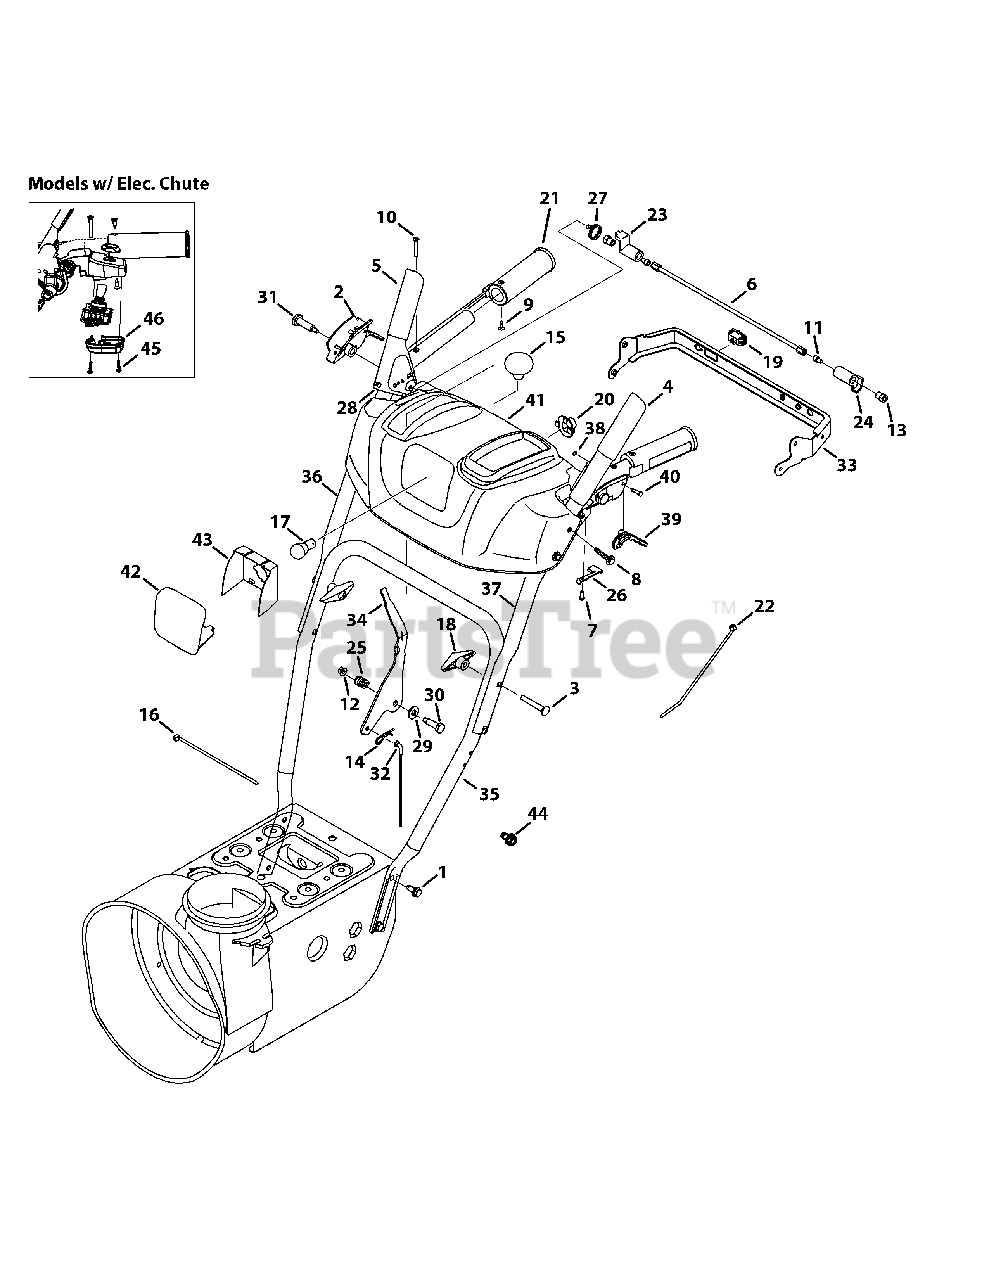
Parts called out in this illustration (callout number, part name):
1	Screw, Taptite, 5/16-18 x .750
2	Clutch Lock, RH (Elec. Chute)
2	Clutch Lock, LH
3	Screw, Carriage, 5/16-18 x 2.50
4	Auger Engage, Red, LH
5	Drive Engage, Red, RH
7	Screw, Plastite, 8-16 x .50
8	Screw, Taptite, 1/4-20 x 1.625
9	Screw, 10-16 x 0.625
10	Screw, 10-24 x 1.375
11	Screw, 1/4-20 x .50
12	Nut, Flangelock, 1/4-20
13	Nut, Hex, 1/4-20
14	Click Pin, .092 x 1.64
15	Shift Knob
16	Cable Tie, 7"
18	Wing Knob, 5/16-18
19	Heated Grip Switch
20	Lamp Socket
21	Heated Grip
22	Cable Tie, Push Mount
23	Plate, Lock
24	Cam, Clutch Lock
25	Compression Spring, .39 x .60 x .88
26	Clutch Lock Spring
27	Torsion Spring, 0.8156 x .3038
28	Rubber Bumper
29	Washer, Flat, .385 x .87
30	Screw, Shield, .374 x 1.05
31	Screw, Shoulder, .437 x 1.345 x 1/4-20
32	Speed Selector Cable
33	Panel Bracket
35	Lower Handle
36	Upper RH Handle
37	Upper LH Handle
39	Steering Trigger Control, Red
40	Steering Trigger Pin, 3/16
41	Handle Panel, Elec. Chute
42	Lens Panel
43	Lens Label
44	Screw, TT, 1/4-20 x .500 (For ground wire)
45	Screw, .159 OD x .610
46	Housing Cover (Elec Chute)
